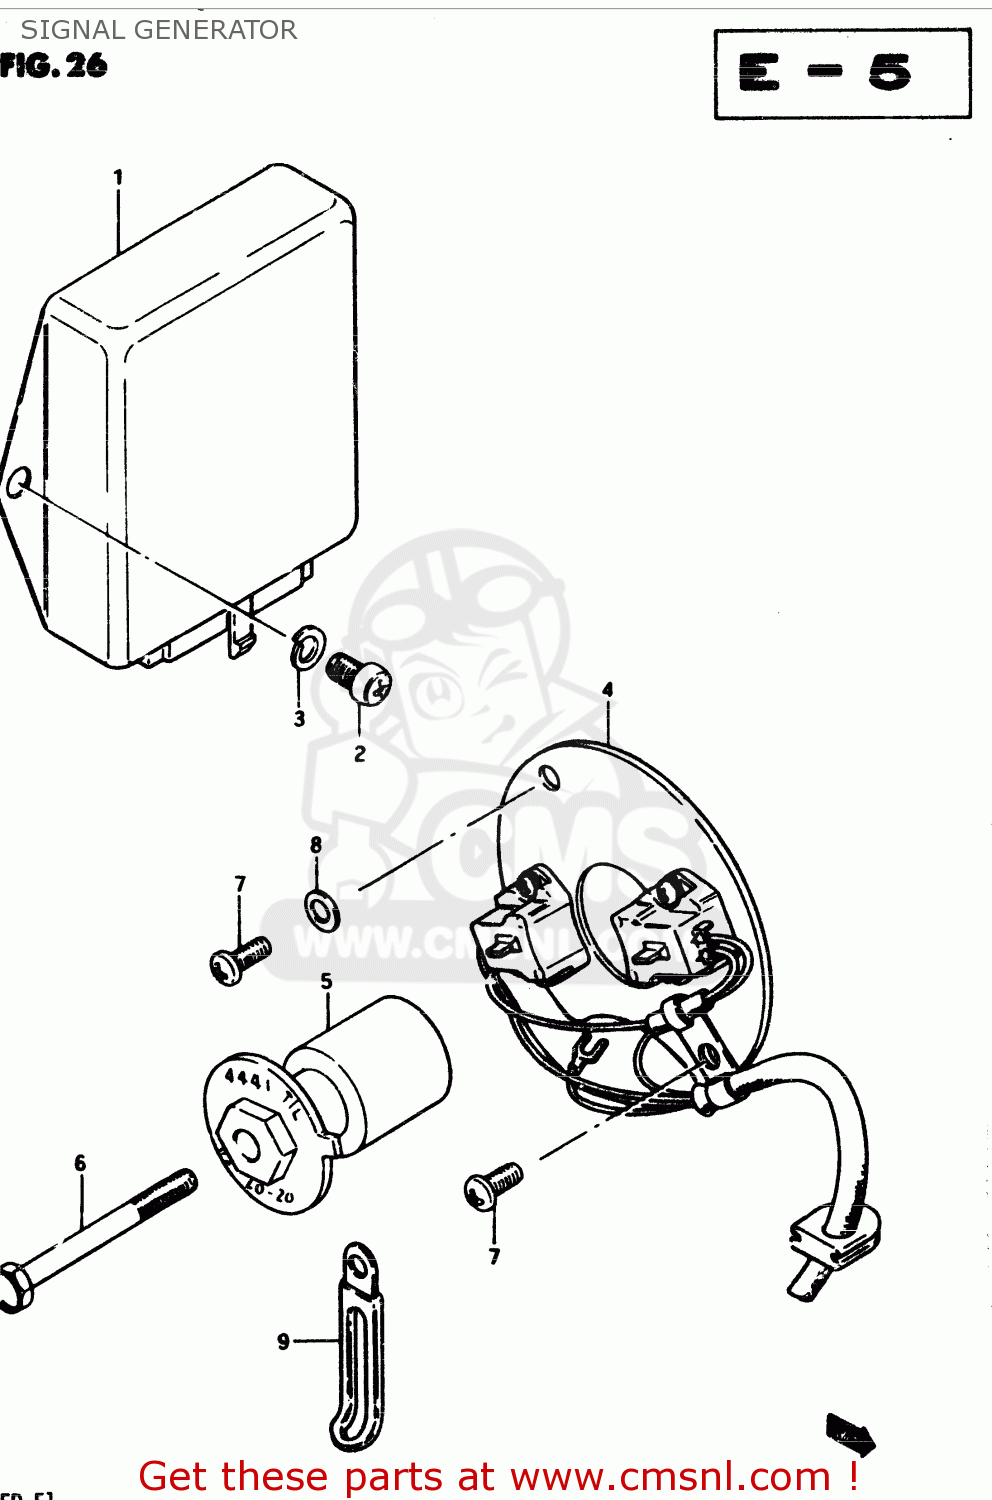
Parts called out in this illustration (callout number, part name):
1	IGNITER UNIT A
2	SCREW
3	LOCK WASHER
4	SIGNAL GENERATOR ASSY
5	ROTOR, SIGNAL
6	BOLT 6X60
7	SCREW(5X12)
8	WASHER
9	CLAMP L:35
